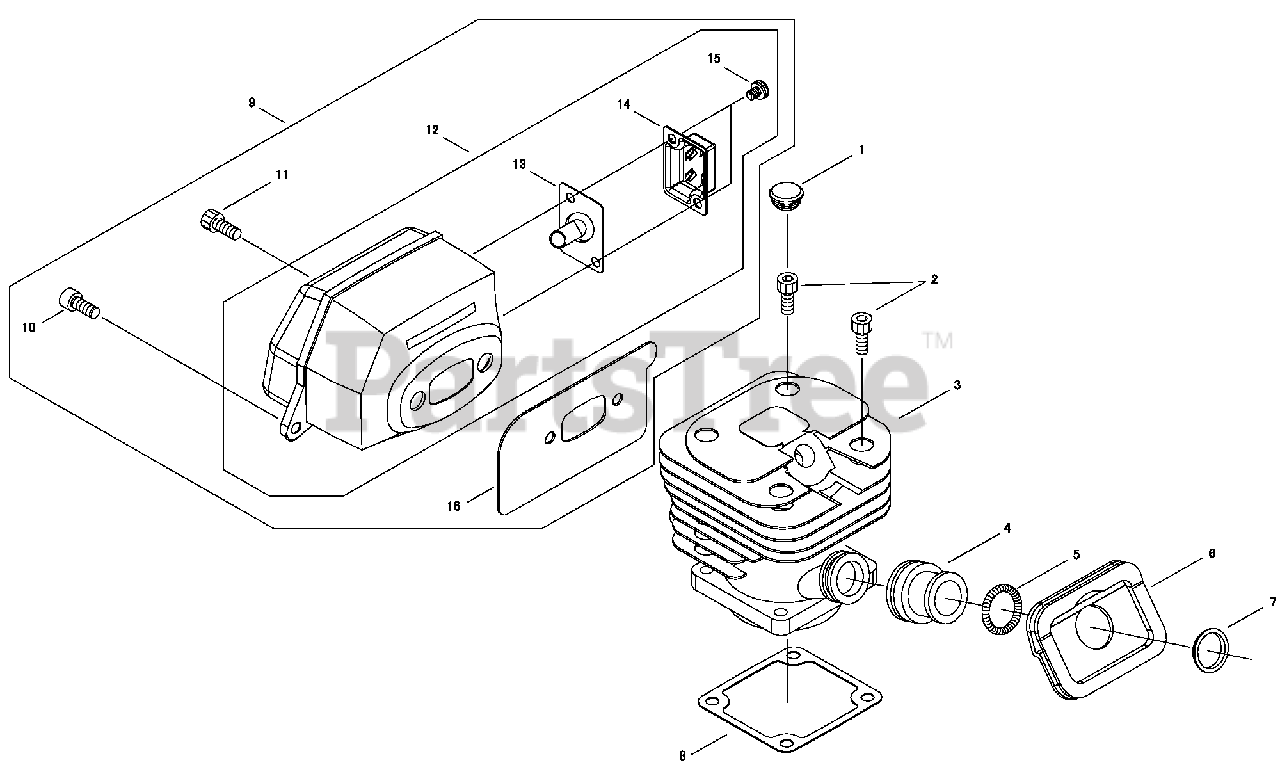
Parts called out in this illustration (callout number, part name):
1	PLUG
2	BOLT M5×18
3	CYLINDER
4	BOOT
5	SPRING
6	SEAL
7	SLEEVE
8	GASKET, CYLINDER
9	MUFFLER ASSY
10	BOLT
11	BOLT M5×18
12	MUFFLER ASSY
13	SCREEN, SPARK ARRESTER
14	COVER, SPARK ARRESTER
15	SCREW M4×6
16	GASKET
